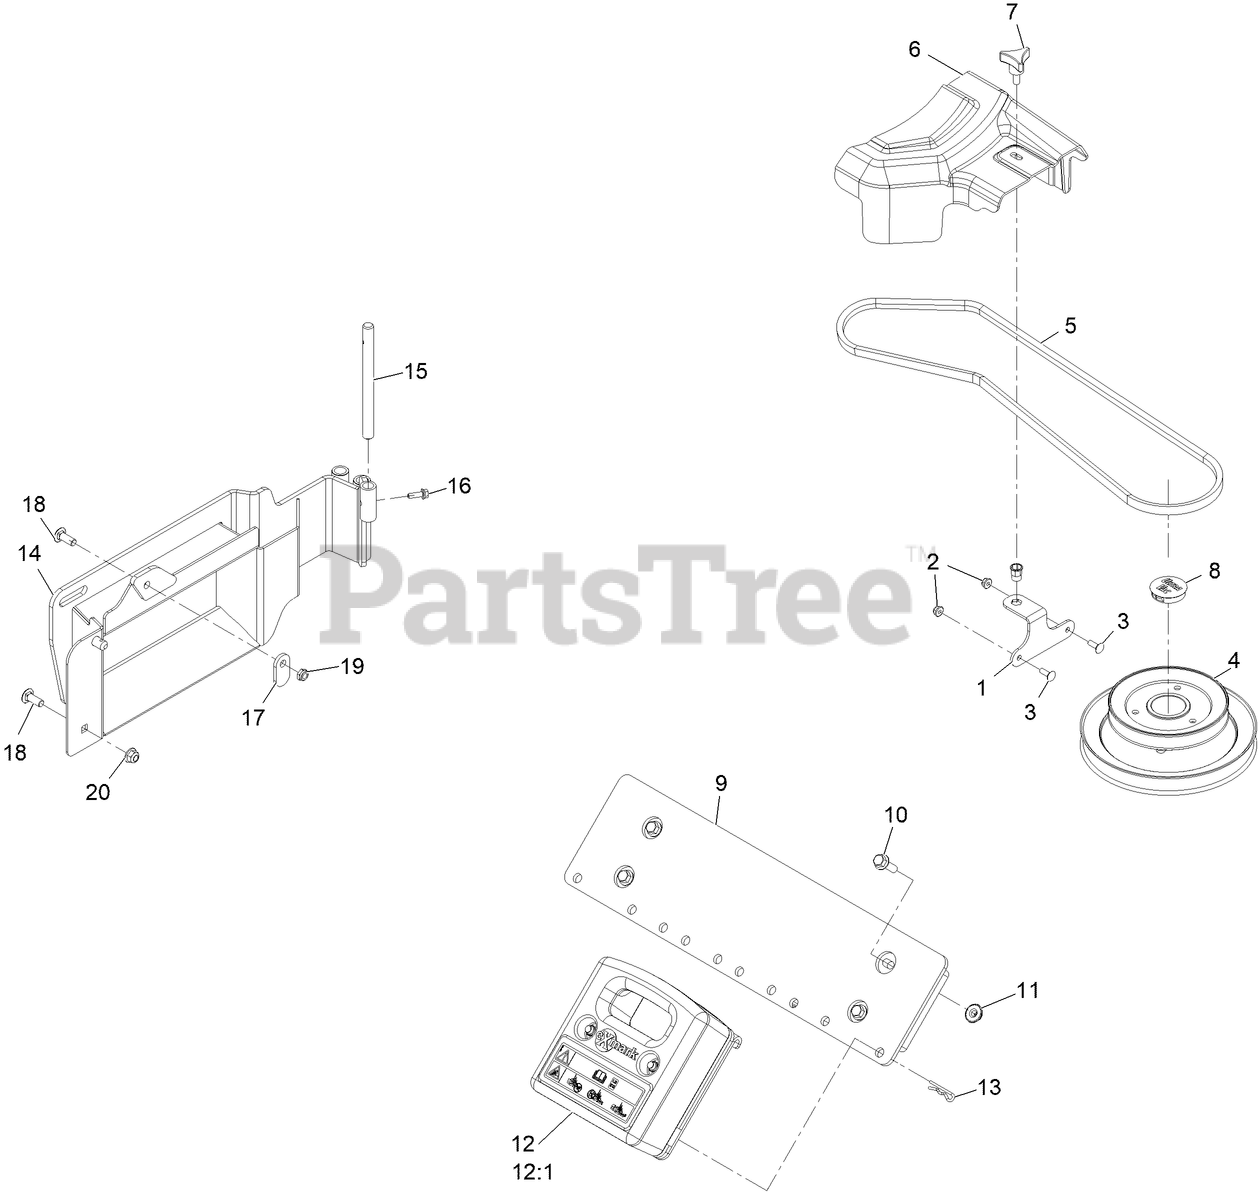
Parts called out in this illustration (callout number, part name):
1	ASM, Bracket W/ Insert
3	BOLT-CARR
4	Jackshaft-Uv Drive 482B Splined
5	BELT, A-SECTION
6	Shield, Belt
8	PLUG, BLACK NYLON 1.75
9	WLD, MOUNT TOEBOARD WEIGHT
10	SCREW-HHF
11	Nut-Nyloc 3/8-16 Flg
12	ASM,CAST WEIGHT
12:1	DECAL-WARNING WEIGHT
13	PIN-HAIR
15	PIN-MOUNT, OCD
16	SCREW-HHF
18	SCREW-CARR
20	NUT-HF, NI
